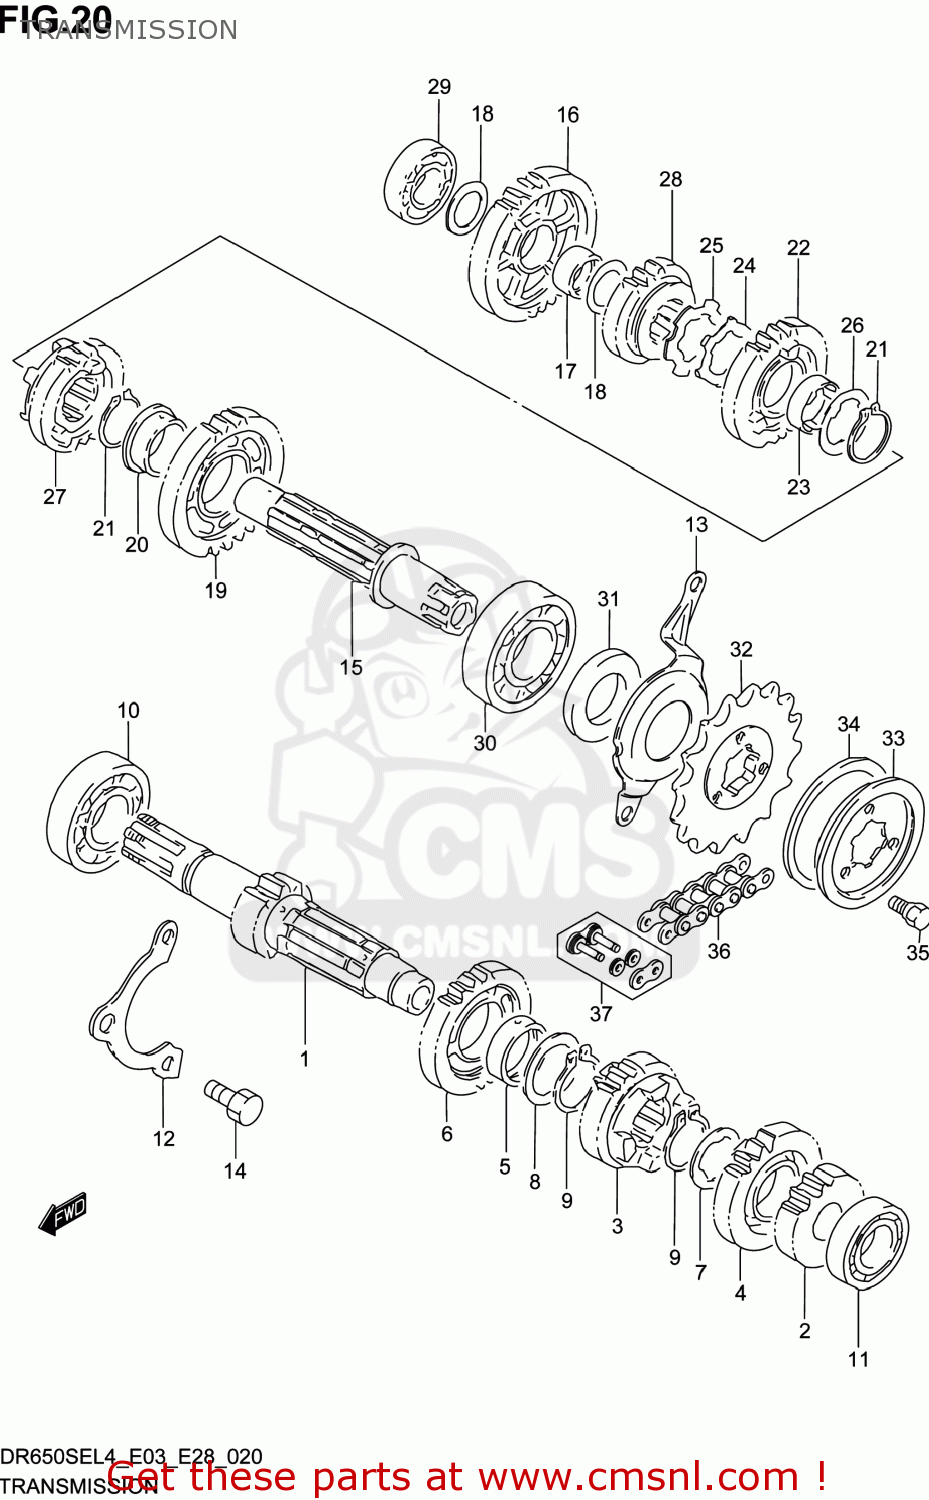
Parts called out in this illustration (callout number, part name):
1	SHAFT SET,CNTR
2	GEAR,2ND DRIVE
3	GEAR,3RD DRIVE
4	GEAR,4TH DRIVE
5	BUSH
6	GEAR,5TH DRIVE
7	WASHER,LOCK
8	SHIM(25X34X1)
9	RING,SNAP
10	BEARING(22X56X16)
11	BEARING(17X40X12)
12	RETAINER,CNTR SHAFT BEARING
13	RETAINER,DRIVE SHAFT OIL SEAL
14	BOLT
15	SHAFT,DRIVE
16	GEAR,1ST DRIVEN
17	BUSH(20X24X13)
18	SHIM(20X30X1)
19	GEAR,2ND DRIVEN
20	BUSH
21	RING,SNAP
22	GEAR,3RD DRIVEN
23	BUSH,DRIVEN GEAR
24	WASHER
25	WASHER,LOCK
26	WASHER,LOCK
27	GEAR,4TH DRIVEN
28	GEAR,5TH DRIVEN
29	BEARING(20X42X12)
30	BEARING(25X62X17)
31	SEAL,OIL(25X44X7)
32	SPROCKET,ENGINE(15T)
33	PLATE,ENGINE SPROCKET
34	DAMPER,ENGINE SPROCKET
35	BOLT(6X13)
36	CHAIN,DRIVE(DID525V9,110L)
37	JOINT SET,CHAIN
